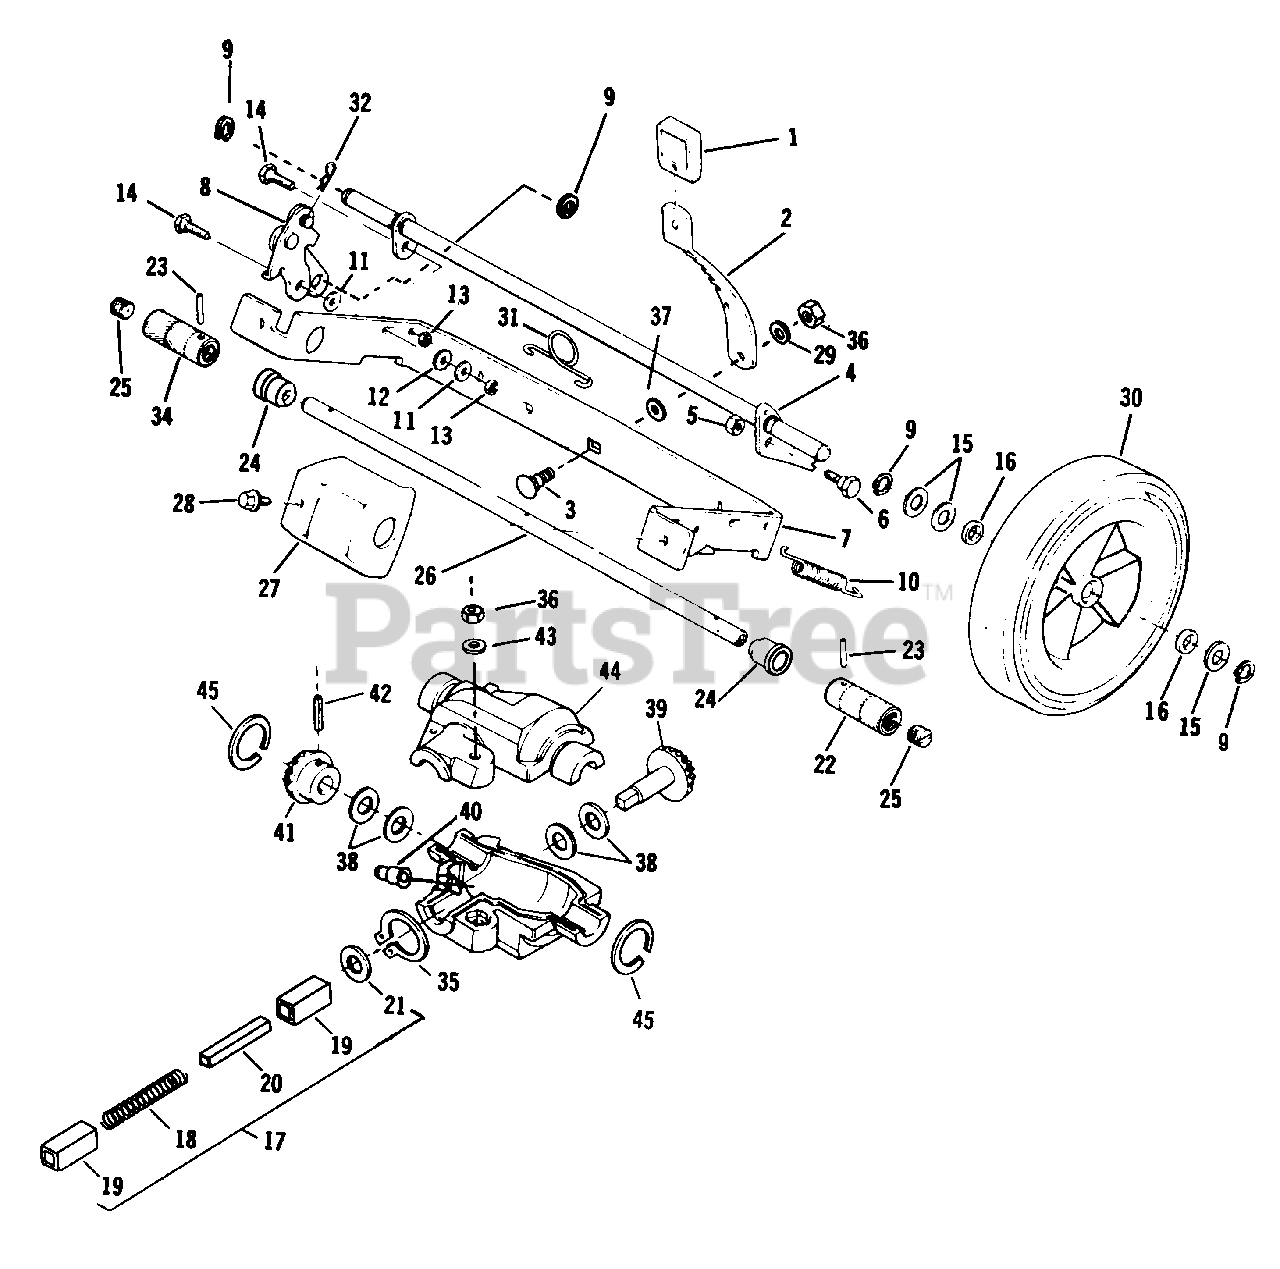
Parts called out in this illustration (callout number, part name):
1	Knob-Rear Height Adj. Lvr.
2	Lever-Rear Height Adj.
3	Shoulder Bolt-Ht. Adj. Lever
4	Axle Assembly
5	Locknut
6	Bolt-Shoulder
7	Bracket-21" Axle
8	Clutch Assembly
9	Retaining Ring
10	Spring
11	Washer
12	Lockwasher
13	Stopnut
14	Bolt-Shoulder
15	Washer
16	Washer-Felt
17	Driveshaft Assembly
18	Spring-Compression
19	Bushing-Driveshaft
20	Driveshaft
21	Washer
22	Drive Roller-L.H.
23	Pin-Spiral
23	Pin-Groove
24	Sleeve and Bearing Assembly
25	Plug
26	Shaft
27	Guard-Roller
28	Screw
29	Washer
30	Wheel-Rear
31	Spring-Height Adjust
32	Lock Pin
33	Retaining Ring
34	Drive Roller-R.H.
35	Ring-Retaining
36	Locknut
37	Washer-Ht. Adj. Lever
38	Washer
39	Gear-Drive
40	Zerk Fitting
41	Gear Driven
42	Spring Pin
43	Washer
44	Gear Box Assembly
45	Ring-Retaining
46	Gear Case-Upper
47	Gear Case-Lower
